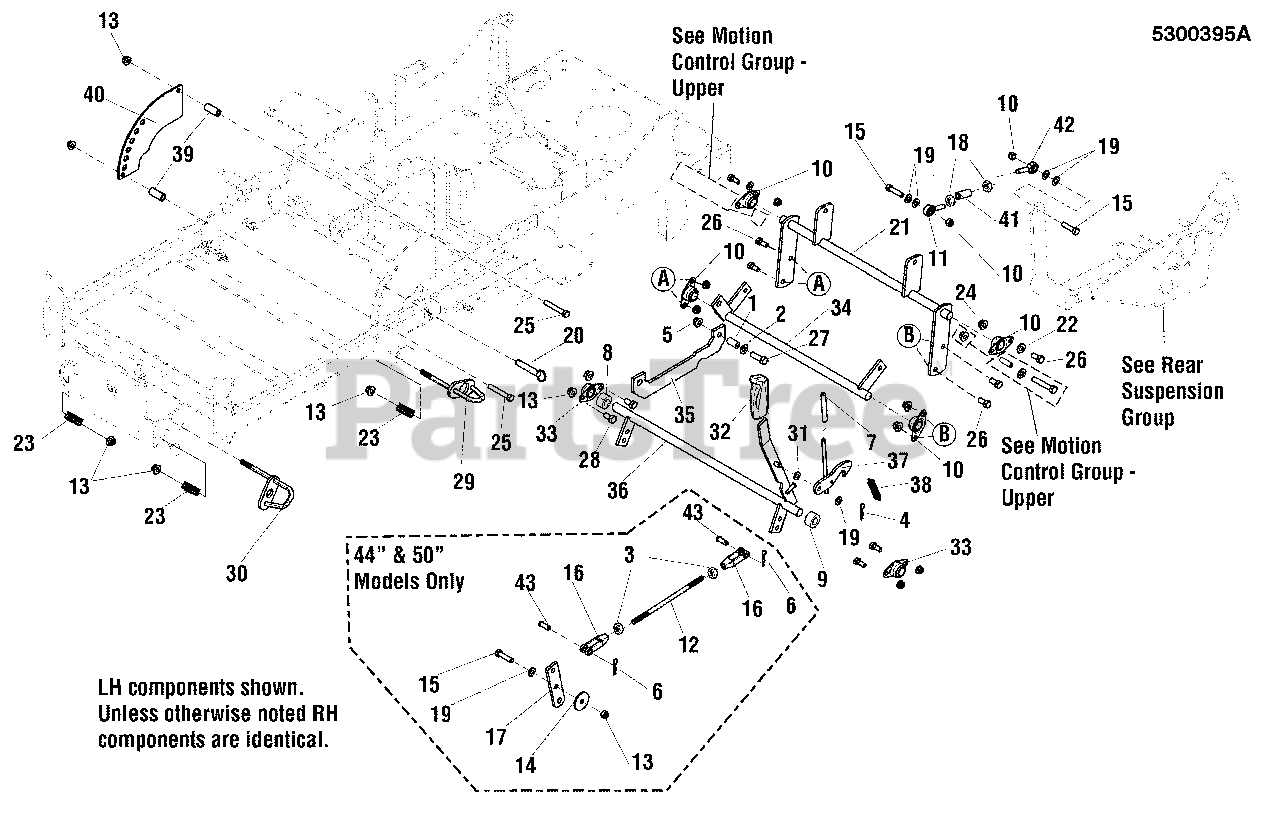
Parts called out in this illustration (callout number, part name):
1	SPACER, .38 X .50 X .38, CZ
2	WASHER, 3/8 SAE
3	NUT, 3/8-24 HEX
4	PIN, COTTER, 1/8 X 3/4
5	NUT, 3/8-16 HEX NYLOCK FLANGE
6	PIN, COTTER, 3/32" X 3/4
7	COVER, VINYL HANDLE
8	SPACER, .76 X 1.00 X 1.00
9	SPACER, .76 X 1.00 X .50, CZ
10	BEARING, BRONZE FLANGE, 3/4"
11	BALL JOINT
12	ROD, LEVER CONNECTING, CZ
13	NUT, 3/8-16 HEX NYLOCK FLANGE
14	WASHER, .41 X 1.75 X .14
15	BOLT, 3/8-16 X 1-1/2 GD5 YZ
16	CLEVIS 3/8-24, PLASTIC
17	LINK, ROLLER REVERSE
18	NUT, 3/8-24 HEX JAM
19	WASHER, 3/8 SAE
20	HITCH PIN ASSEMBLY, 1/2" X 2.50"
21	WELD, COMPENSATOR ASSM. - ORG
22	WASHER, 5/16" SAE
23	SPRING-COMP, .594ID X 2.68LG X .080WR
24	NUT, 5/16-18 HEX NYLOCK FLANGE
25	BOLT, 3/8-16 X 2-1/4 GD5 YZ
26	BOLT, 5/16-18 X 3/4 GD5
27	BOLT, 3/8-16 X 1-1/4 GD5
28	BOLT, 3/8-16 X 3/4 GD5 YZ
29	WELD, QUICK RELEASE HANDLE, REAR - ORG.
30	WELD, QUICK RELEASE HANDLE - ORG
31	WASHER,WAVE,M10
32	GRIP, BLACK FLEXIBLE
33	BEARING, BRONZE FLANGE, 3/4
34	WELD, DECK LIFT HANGER REAR - ORG
35	LINK, DECK LIFT - ORG
36	WELD, DECK HEIGHT SHAFT - ORANGE
37	WELD, DECK LOCK
38	SPRING-EXT, .500 OD X 3.50 LG X .058 WR
39	SPACER, .39 X .63 X 1.50, CZ
40	PLATE, DECK HEIGHT- INNER -ORG
41	SLEEVE, .32 X .63 X 1.50, TAPPED 3/8-24
42	BALL JOINT, 3/8-24 MALE
43	PIN, CLEVIS, 3/8 X 1, CZ
